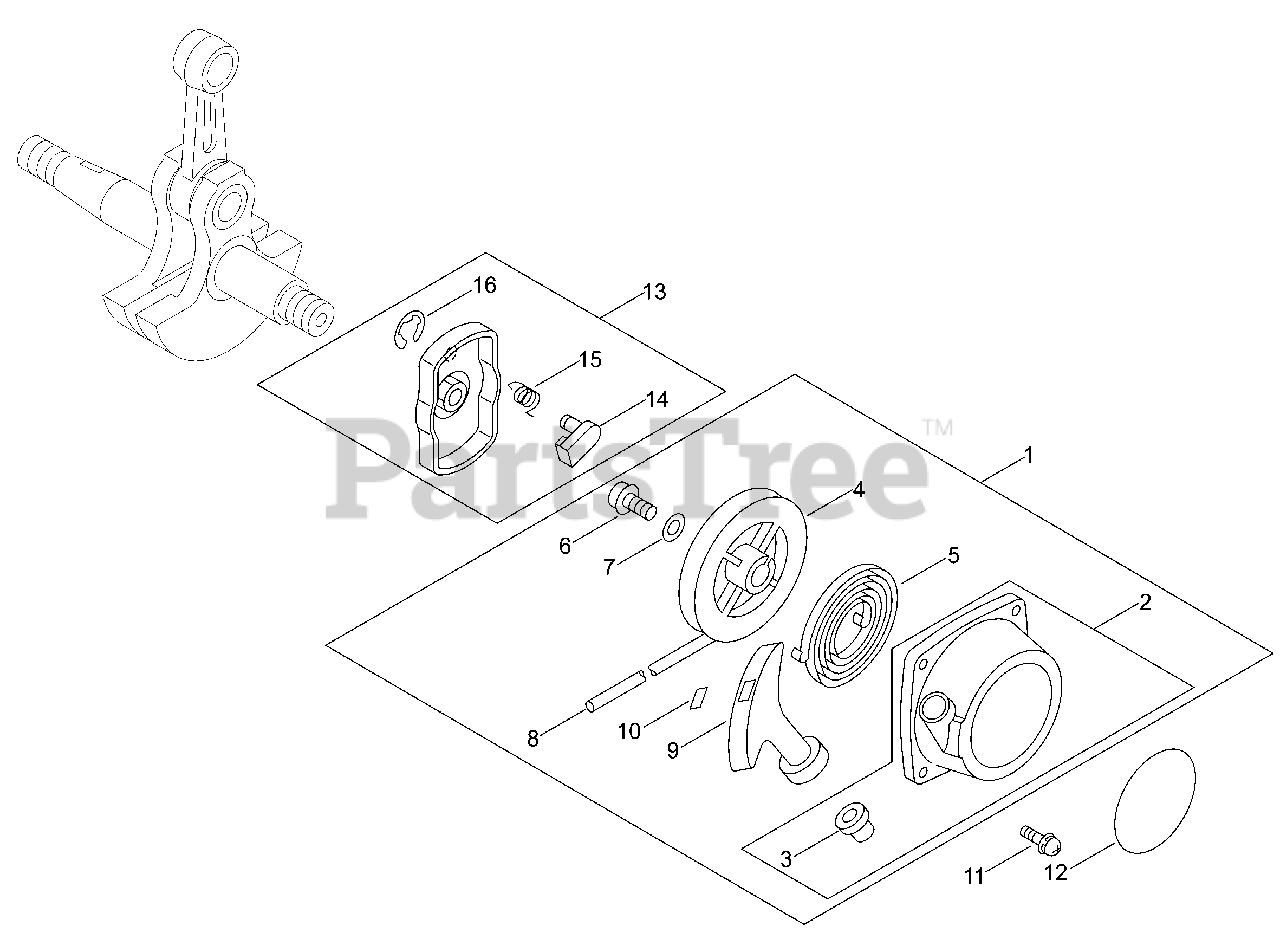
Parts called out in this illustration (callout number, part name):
1	STARTER ASSY, RECOIL
2	+CASE, STARTER
3	++GUIDE, ROPE
4	+REEL, ROPE
5	+SPRING, RECOIL
7	+WASHER
8	+ROPE, STARTER 3.8×1400
9	+GRIP, STARTER
10	+RETAINER, ROPE
11	SCREW 4×18
12	LABEL, ECHO
13	PAWL ASSY, STARTER
14	+PAWL, STARTER
15	+SPRING, RETURN
16	+E-RING 4
